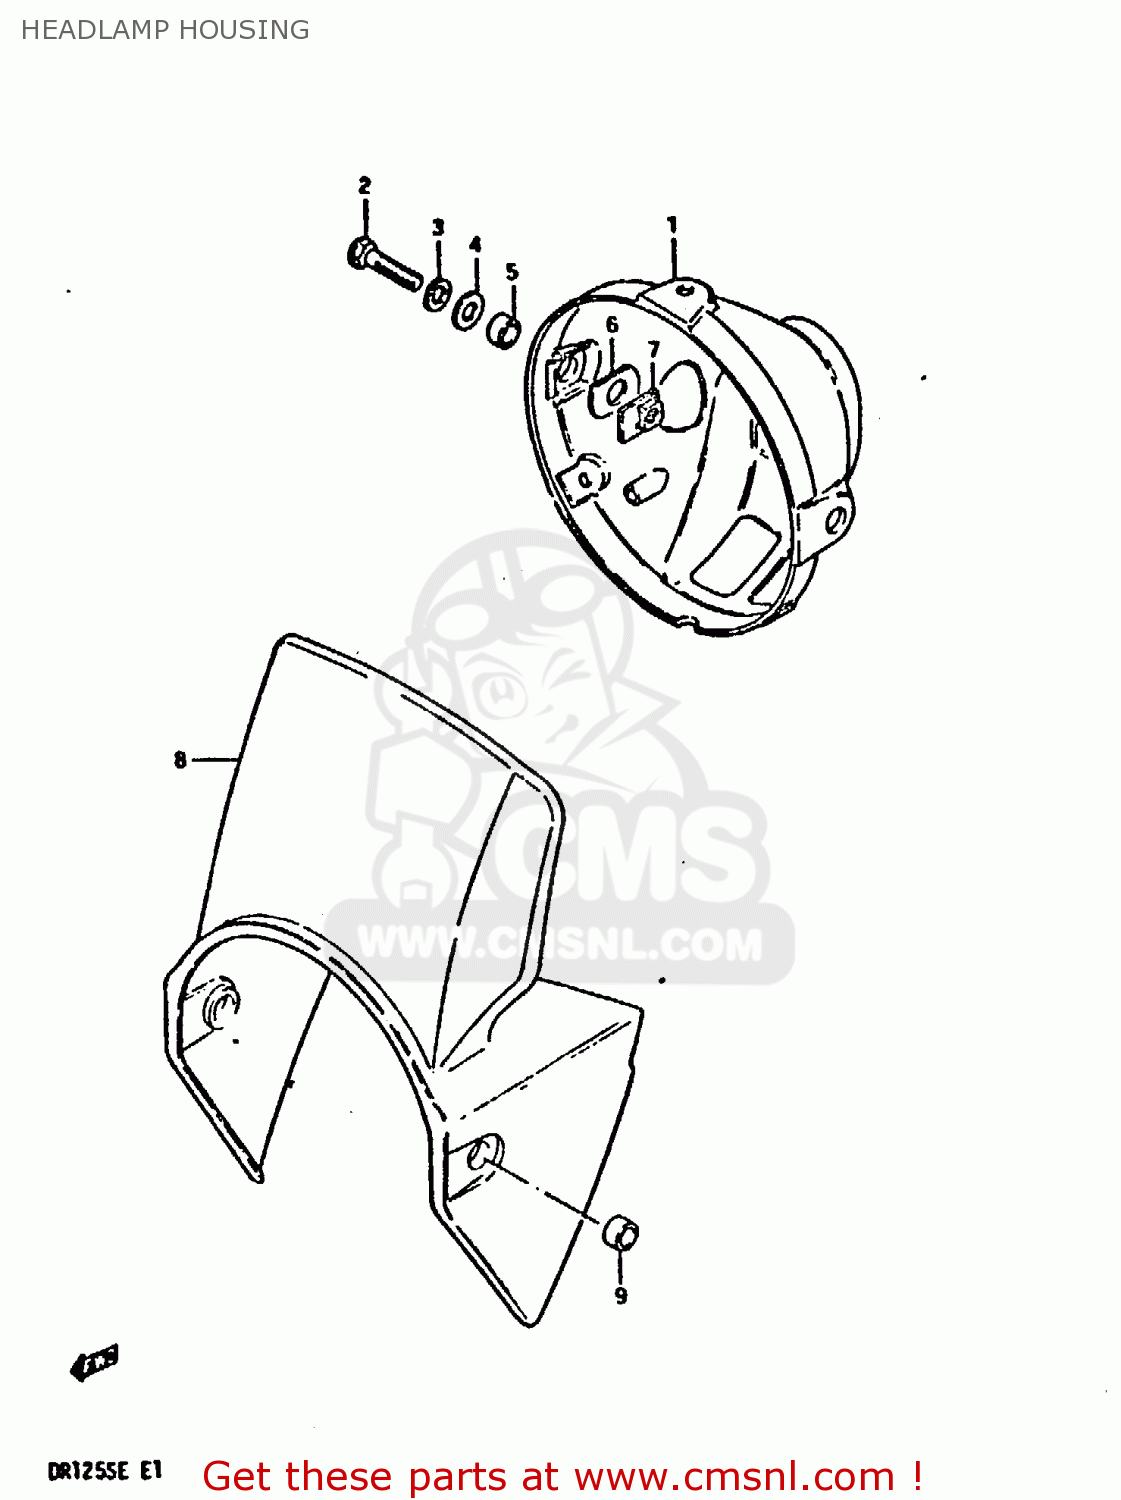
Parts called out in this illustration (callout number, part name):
1	HOUSING,HEAD LAMP
2	BOLT
3	LOCK WASHER
4	WASHER
5	SPACER (8.8X12X7)
6	CUSHION
7	PLATE,HEADLAMP HOUSING
8	COVER,HEAD LAM
9	SPACER (8.8X12X7)
